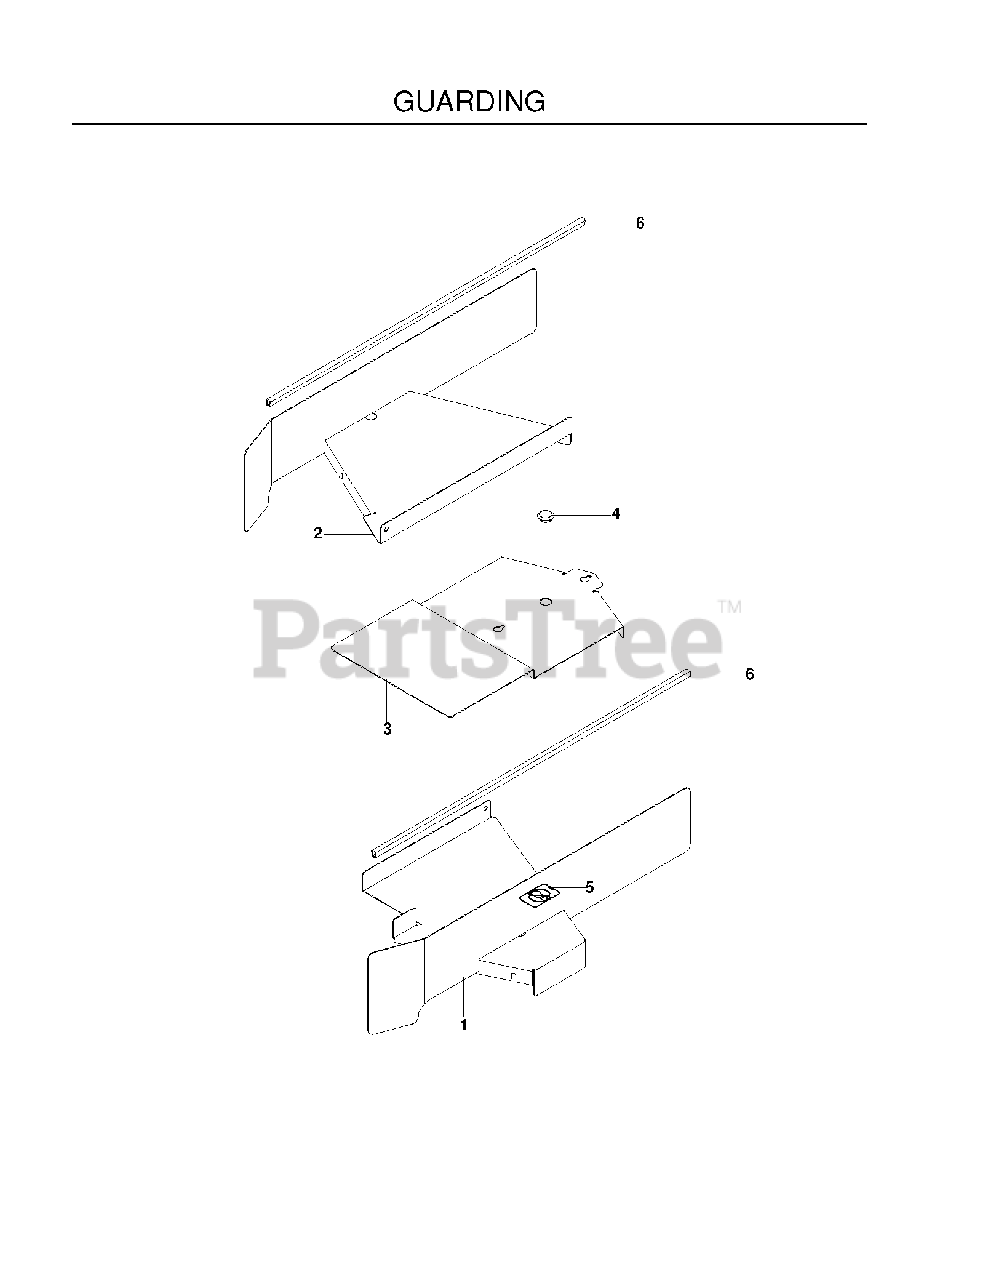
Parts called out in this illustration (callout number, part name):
4	PLUG, BUTTON HOLE
5	DECAL, NO STEP
6	FLEX TRIM, BLACK
